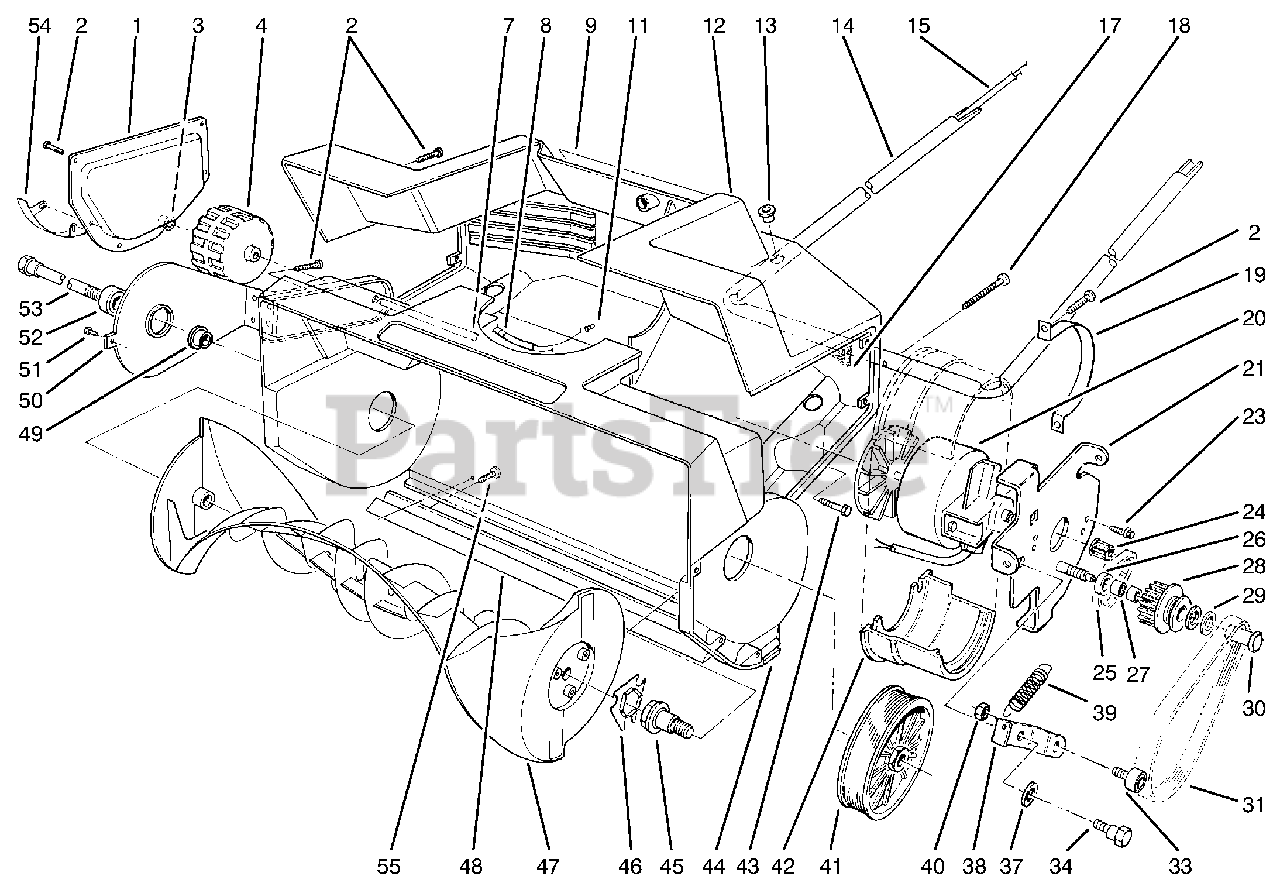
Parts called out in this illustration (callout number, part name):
1	Plate - Side
2	SCREW-PPH
3	PUSHNUT-CAP, WASHER
7	Shaft - Axle
8	Relief - Strain
9	Decal - Danger
11	Connector
12	Shroud - Housing
14	Tube - Lower Handle
15	Wire Harness
17	Filter - Foam
18	Screw - Pan Hd.
19	Strap - Motor
21	Motor Plate ASM
23	Screw - Hex Washer Hd.
24	Pulley - Driver
25	Belt - Timing
27	Bearing-Needle
28	Pulley Assembly-Idler (Incl. Ref. #27)
29	WASHER-THRUST
30	Bolt - Idler
31	Belt - Drive
33	Bearing Assembly (Incl. Ref. #40)
34	SCREW-SHOULDER
38	Bracket - Idler
40	NUT-LOCK, NI
41	Pulley - Driven
42	Clamp - Motor Bracket
44	Housing - Rotor
45	Shaft - Rotor Driver
46	Coupler - Rotor
50	Bracket-Wheel (Incl. Ref. #52)
51	RIVET-POP
52	Bearing - Ball
53	Shaft - Rotor
54	Skid - Housing
55	Screw - Pan Hd.
